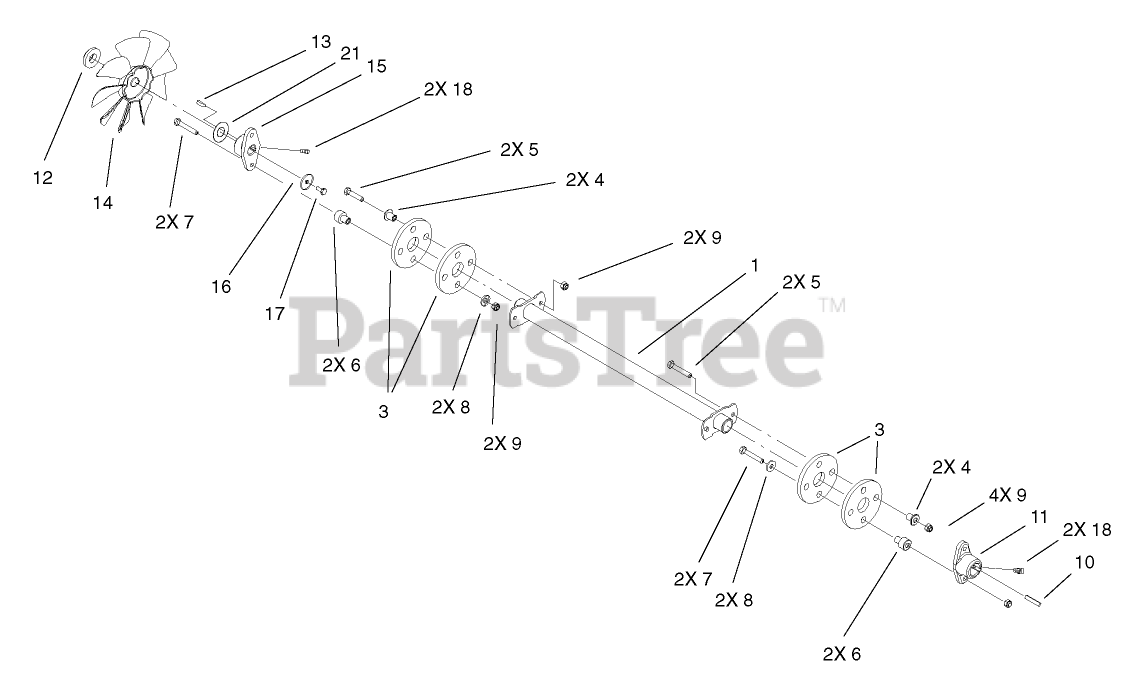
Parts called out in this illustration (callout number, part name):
1	SHAFT-DRIVE
3	COUPLING-RUBBER
4	SPACER
5	SCREW-HH
6	SPACER
7	SCREW-HH
8	WASHER-FLAT
9	NUT-LOCK, NI
10	KEY-SQUARE
12	SPACER-FAN
13	KEY-WOODRUFF
14	FAN-HYDRO
16	WASHER
17	SCREW-HH
18	SCREW-SET
21	WASHER - FAN
